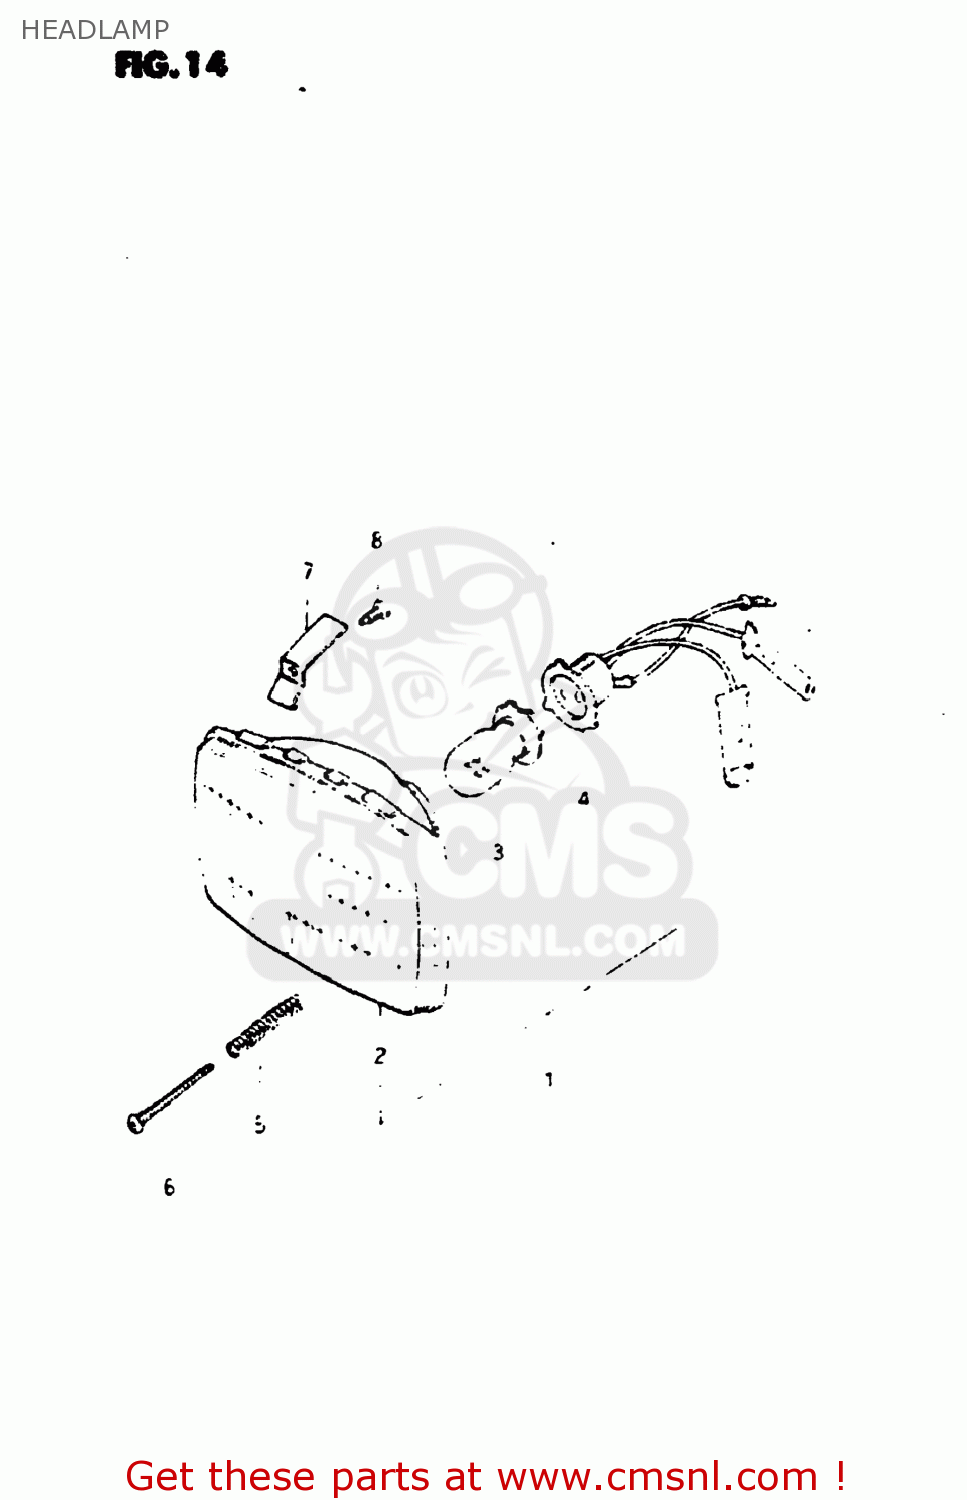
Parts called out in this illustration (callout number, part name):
1	HEADLAMP ASSEMBLY
2	LAMP UNIT
3	BULB(6V15/15W/STANLEY,A3598HA)
4	SOCKET,HEADLAMP
5	SPRING,HEAD LAMP ADJUSTER
6	SCREW,HEADLAMP ADJUST
7	SPRING
8	SPRING,HEADLAMP ADJUST
